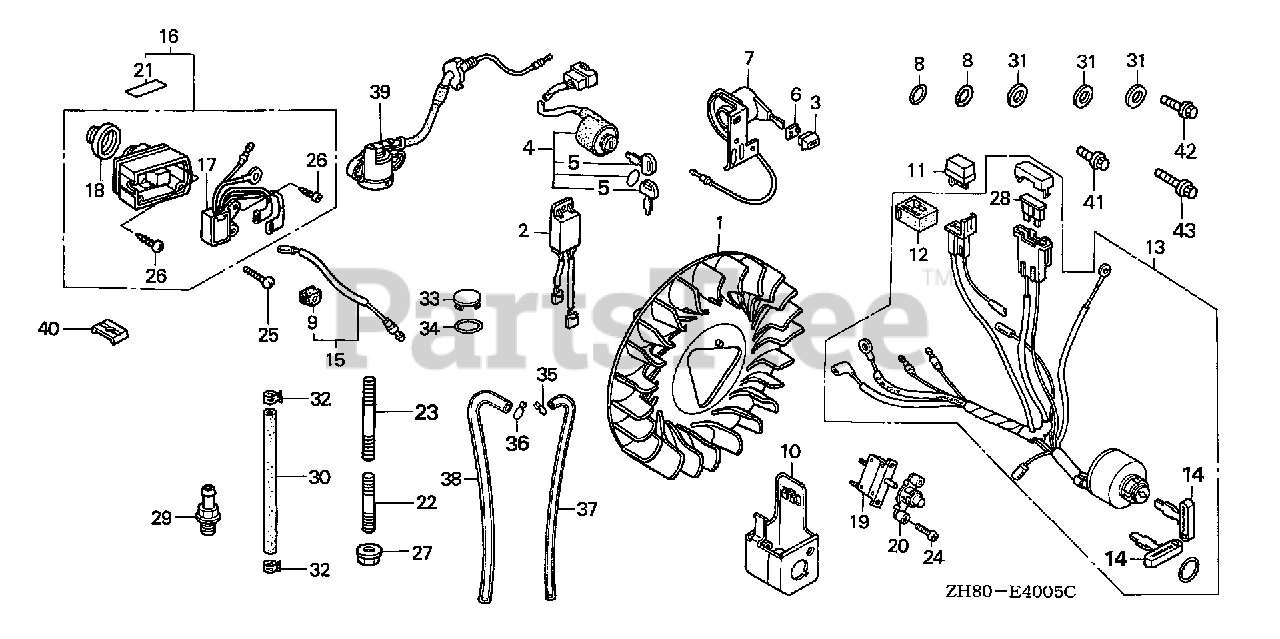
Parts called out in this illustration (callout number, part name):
3	KNOB, PETCOCK LEVER
6	BUSH, CONTROL KNOB
7	SWITCH ASSY., ENGINE
